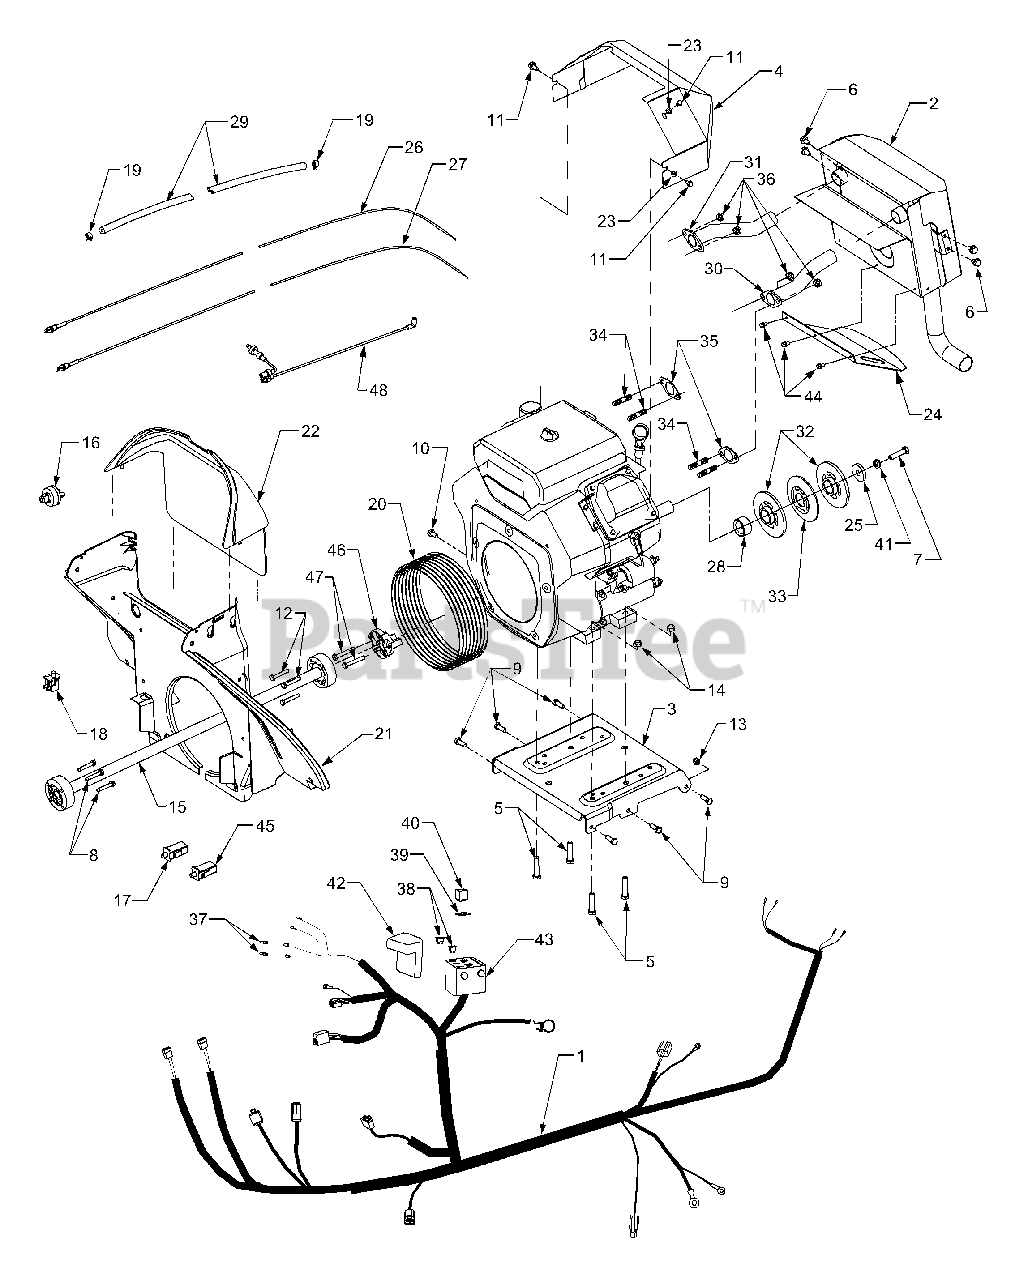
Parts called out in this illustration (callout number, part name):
1	Harness, Wire
2	Muffler Assembly
3	Plate, Engine Mounting
4	Shield, Muffler Heat
5	Screw, Hex Cap, 3/8-24 x 1.75 GR5
6	Screw, Hex Wash. Hd. Tapp 5/16-18 x .5
7	Screw, Hex Cap, 7/16-20 x 1.5 GR5
8	Screw, Hex Cap Lock 1/4-20 x 1.25 GR5
9	Screw, Hex Cap, 5/16-18 x .875 GR5
10	Screw, Hex Cap, 5/16 - 24 x .625 GR5
11	Screw, Hex Cap, M6 - 1.0 x 10MM
12	Screw, Hex Cap, Lock 1/4-20 x 1.62 GR5
13	Nut, Hex Insert Lock, 5/16-18
14	Nut, Hex Lock, 3/8-24
15	Shaft, Drive, 27.125 Long
16	Switch, Key, w/Groung
17	Switch, Plunger (Reverse)
18	Switch, Snap Mount (Seat)
19	Clamp, Hose
20	Boot, Intake
21	Baffle, Lower Air
22	Baffle, Upper Air
23	Washer, Flat, .281 x .50 x .06
24	Shield, Lower Exhaust
25	Washer, Flat, .417 x 1.5 x .225
26	Cable, Throttle Control
27	Cable, Choke Control
28	Spacer, Crankshaft
29	Hose, Fuel Line
30	Pipe, Exhaust RH
31	Pipe, Exhaust LH
32	Pulley Half
33	Pulley, Center
34	Stud, M8 - 1.25 x 33MM
35	Gasket, Exhaust
36	Nut, Hex, M8 x 1.25
37	Bulb, Indicator
38	Fuse, 25 Amp
39	Gasket, Silicone
40	Relay
41	Washer, Lock, 7/16
42	Cover, Fuse Box
43	Box, Fuse
44	Screw, Hex Wash. Hd. Tapp, #12-24 x .38
45	Switch, Plunger (Brake)
46	Adapter, Drive Shaft
47	Screw, Hex Flange, M10 x 1.5 x 90
48	Hose, Vacuum
